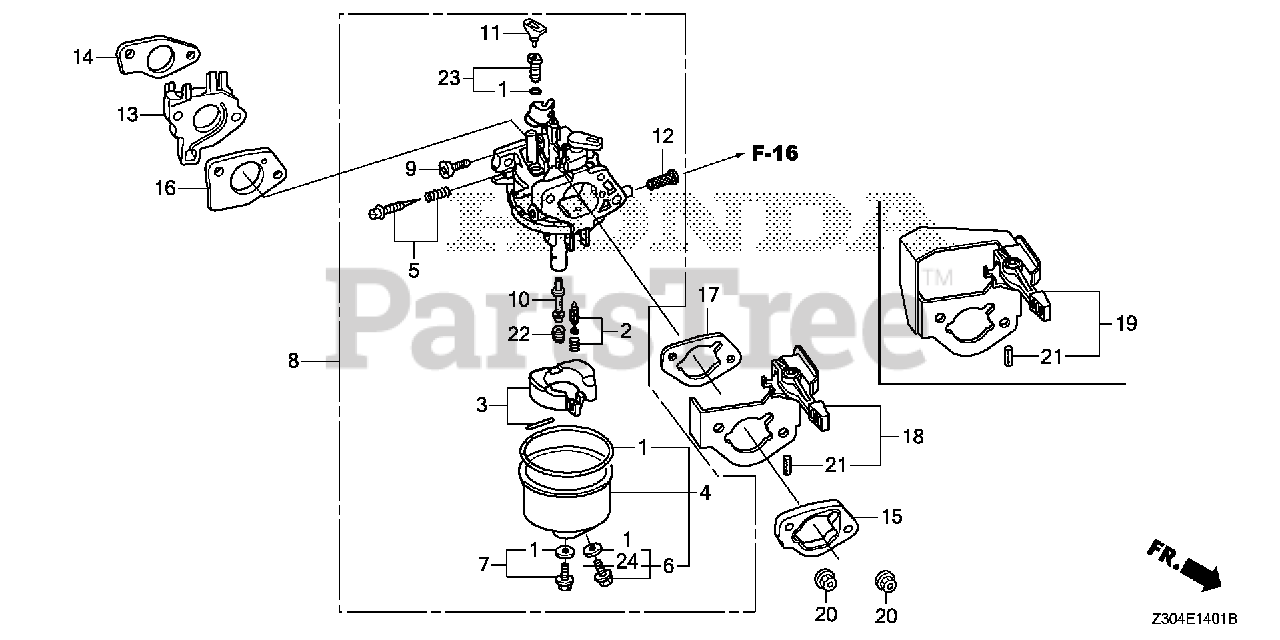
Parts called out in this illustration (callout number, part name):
1	GASKET SET
2	VALVE SET, FLOAT
4	CHAMBER SET, FLOAT
6	SCREW SET, DRAIN
7	SCREW SET
8	CARBURETOR ASSY. (BE95A A)
9	SCREW, THROTTLE STOP
10	NOZZLE, MAIN
11	COLLAR, SETTING
12	SCREEN, FUEL STRAINER
13	INSULATOR, CARBURETOR
14	GASKET, CARBURETOR INSULATOR
15	SPACER, CARBURETOR
16	GASKET, CARBURETOR
17	GASKET, AIR CLEANER
18	BASE, CHOKE
20	NUT, FLANGE (6MM)
21	PIN, SPRING (2X12)
22	JET, MAIN (#98)
22	JET, MAIN (#102)
22	JET, MAIN (#105)
23	JET SET, PILOT (#40)
24	WASHER, PLAIN (6.2X10.7 DRAIN)
